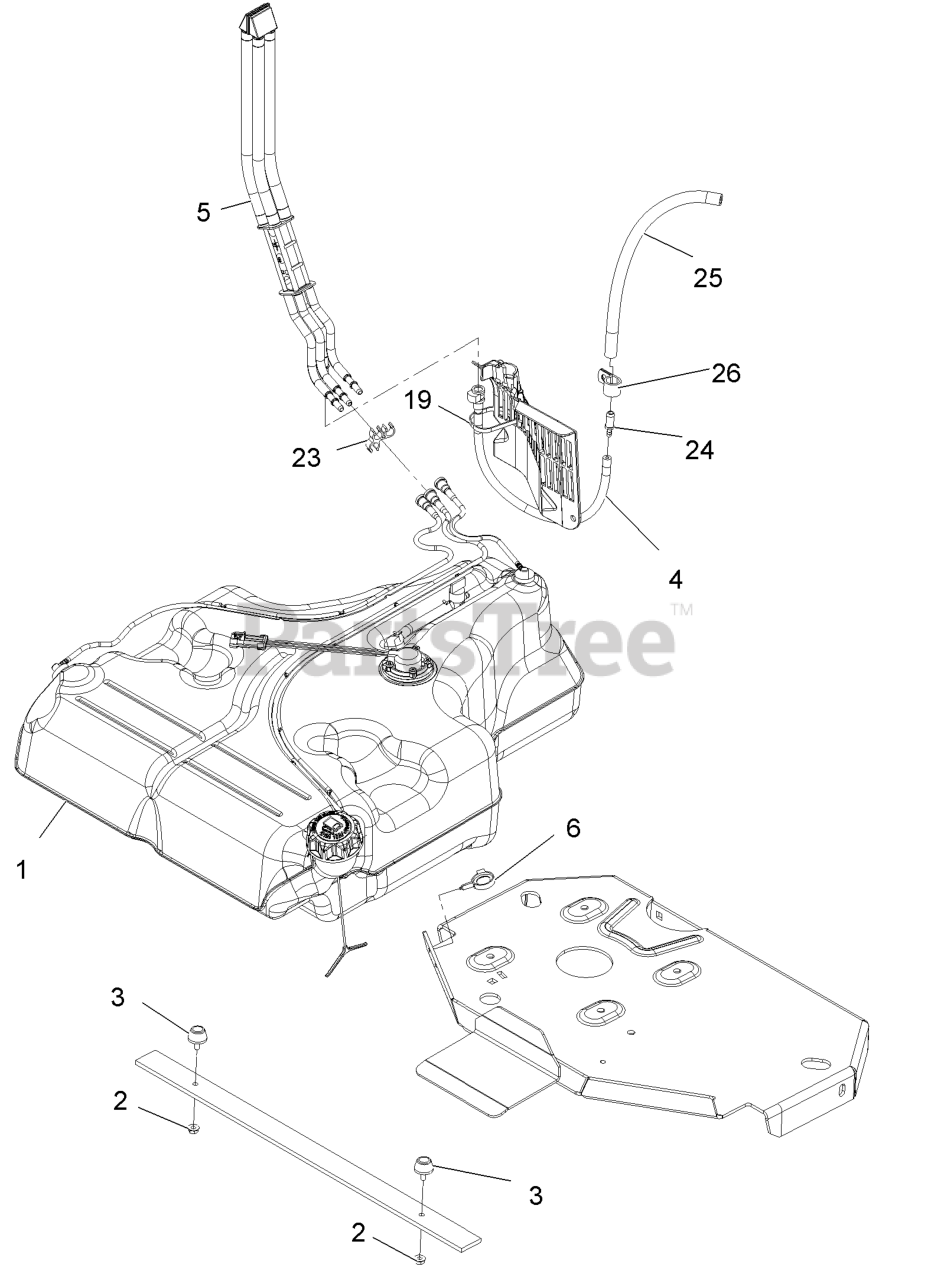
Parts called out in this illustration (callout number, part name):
3	BUMPER-RUBBER
4	HOSE ASM
5	FUEL MANIFOLD VENT ASM
6	CLAMP-HOSE
19	TIE-PLASTIC
23	CLIP-SPACER
24	FITTING-STRAIGHT
25	HOSE-FUEL
26	CLIP-LOOM
